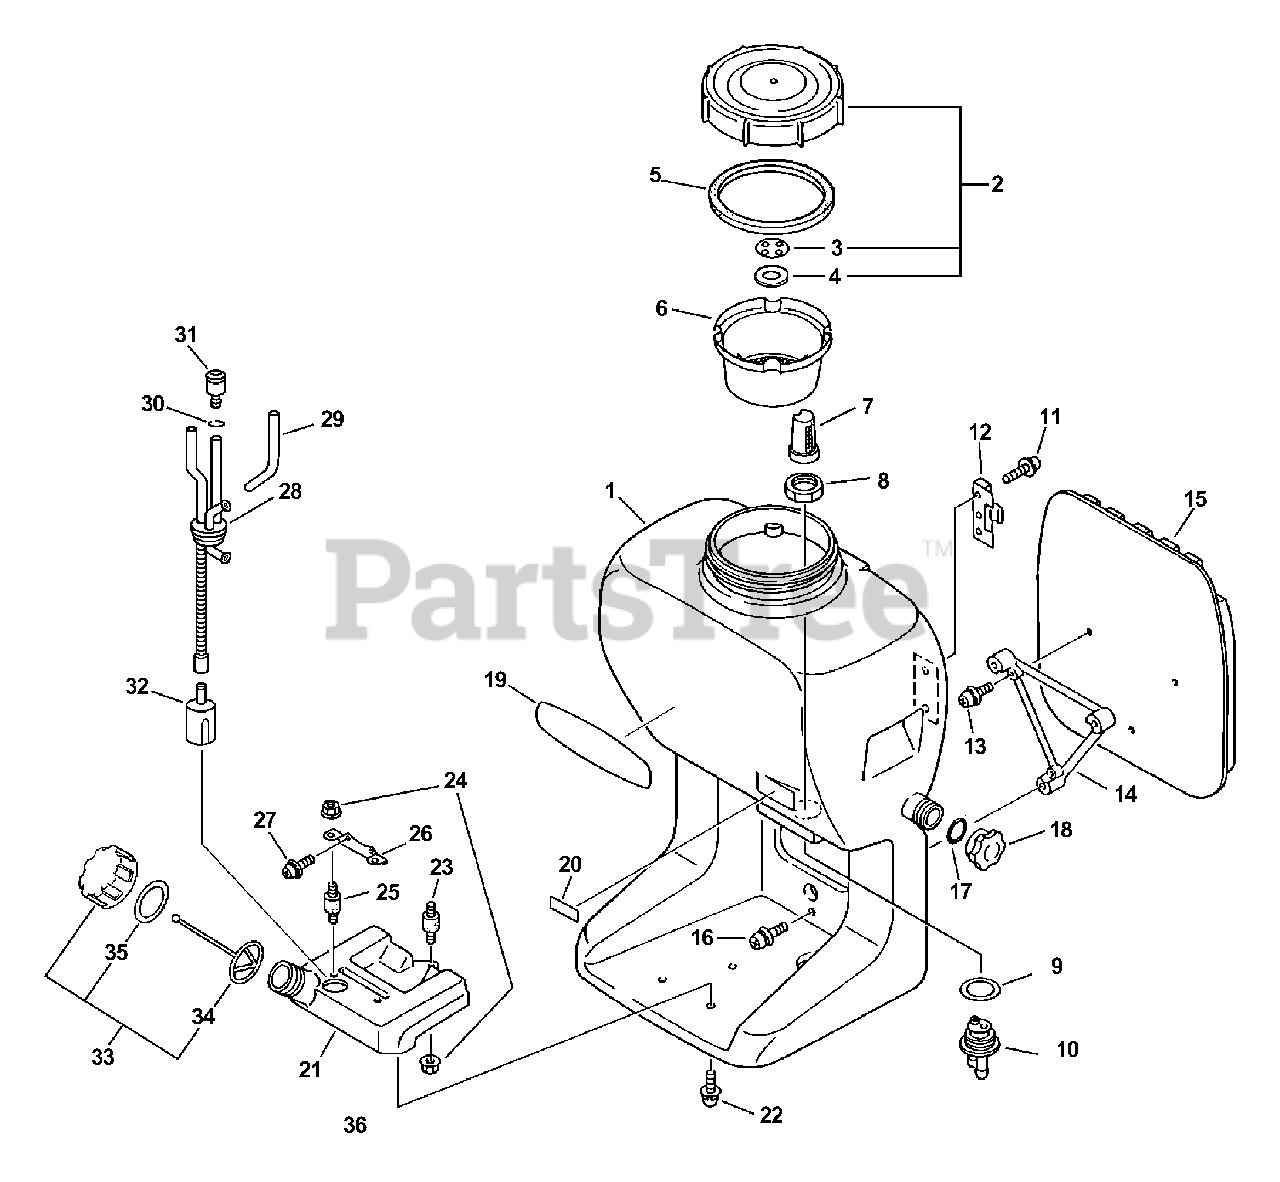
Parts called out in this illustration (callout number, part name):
1	TANK, CHEMICAL
2	CAP ASSY, SPRAYER TANK
3	VALVE, AIR
5	GASKET, CHEMICAL TANK
6	FILTER, CHEMICAL TANK
8	NUT, HOSE
9	GASKET, CIRCULAR
11	SCREW 6×20
12	HOLDER, SPRAYER WAND
13	SCREW 5×16
14	BRACKET, CUSHION
15	CUSHION, BACKPACK
16	SCREW 5×16
18	CAP, DRAIN
19	LABEL, ECHO
20	LABEL, MODEL
21	TANK, FUEL
22	SCREW 6×14
24	NUT, FLANGE M6
26	BASE, SWIVEL
27	SCREW 5×10
28	PIPE, FUEL
29	PIPE, FUEL 3×6×100
31	VENT ASSY
32	FILTER, FUEL
33	CAP ASSY, FUEL
34	CONNECTOR, CAP L= 100 MM
35	GASKET, FUEL CAP
